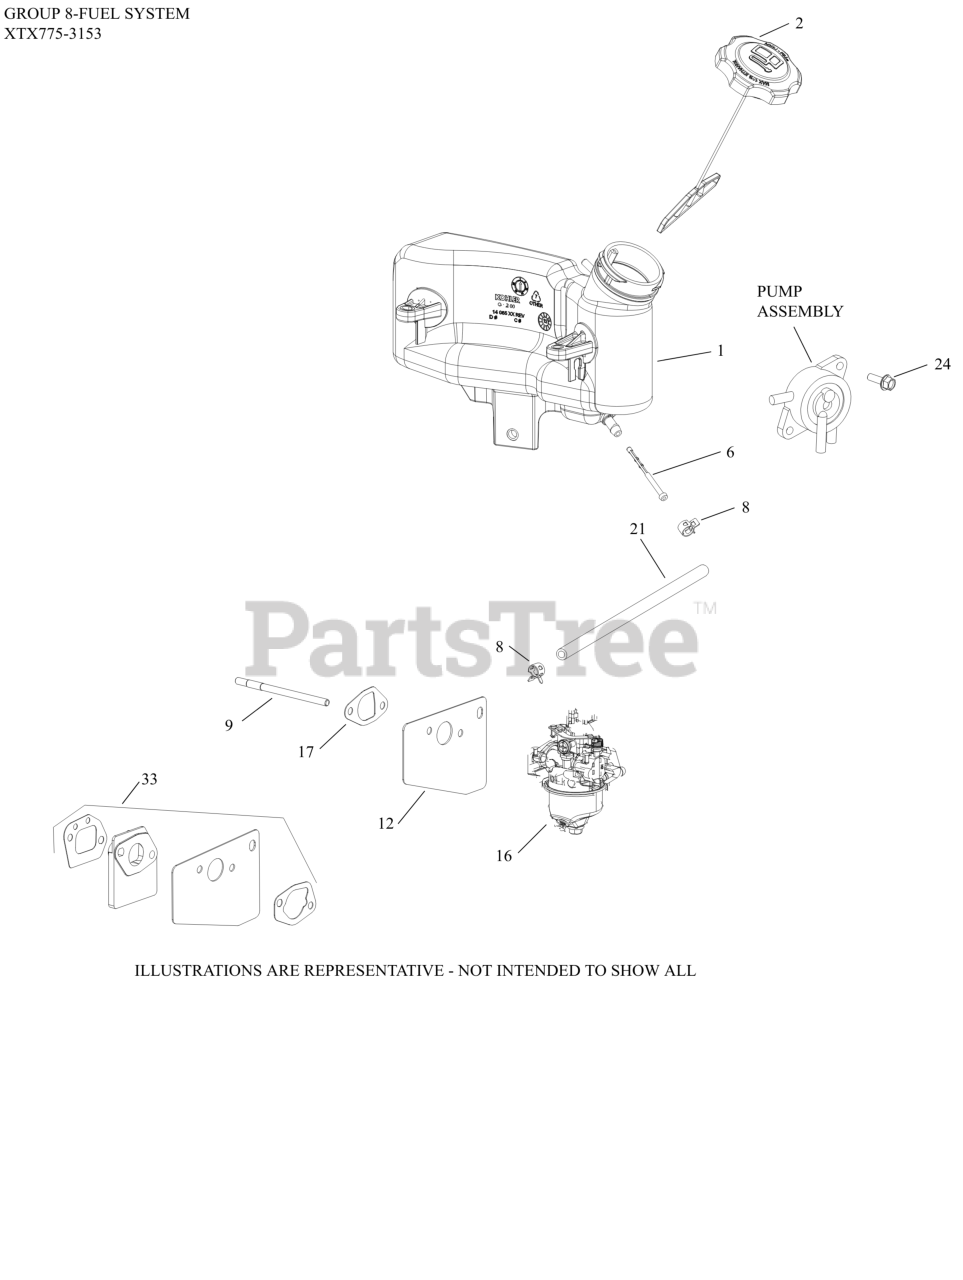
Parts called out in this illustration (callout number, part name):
1	TANK, FUEL
2	FUEL CAP ASSEMBLY
6	FILTER, FUEL IN-NIPPLE
8	CLAMP, HOSE (NON-CALIF)(#1423710S)
9	STUD, M6X1.0X93.8MM
12	KIT, CARBURETOR HEAT SHIELD GASKET
16	KIT, CARBURETOR 13 MM STD CHOKE
17	KIT, INTAKE GASKET
21	HOSE, FUEL LOW-PERMEATION
24	SCREW, HEX FLANGE (M6)
33	KIT, CARBURETOR SPACER
NI	KIT, HIGH ALTITUDE - USE 14 755 04-S
NI	KIT, CARBURETOR REPAIR (RUIXING)
